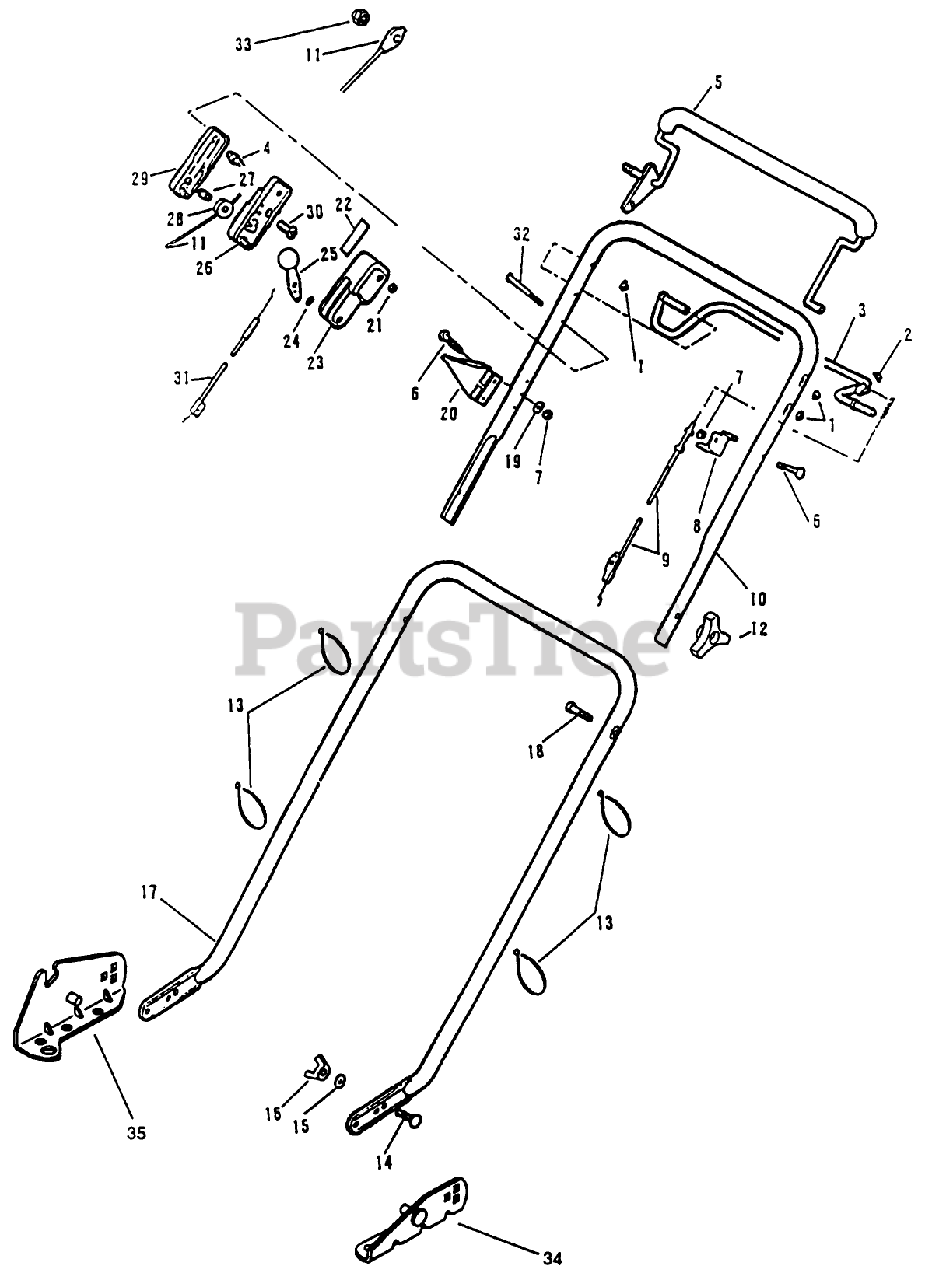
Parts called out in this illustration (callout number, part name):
4	COLUMN
5	CONTROL LEVER ARG
7	LOCKNUT E
8	ANCHOR C'DUIT TRO
9	CABLE - CONTROL
11	CONTROL CABLE
13	TIE-CABLE
16	NUT WING
17	HANDLE-LOWER(GREEN *
19	WASHER
21	NUT C/LOCK E
24	WASHER-SPRING
25	LEVER&KNOB AY WES
27	PIN SKF
28	PULLEY PL
29	OUTER CONTROL CASE
30	SCREW
31	CABLE TH'TTLE WES
32	SCREW
33	NUT ACORN
